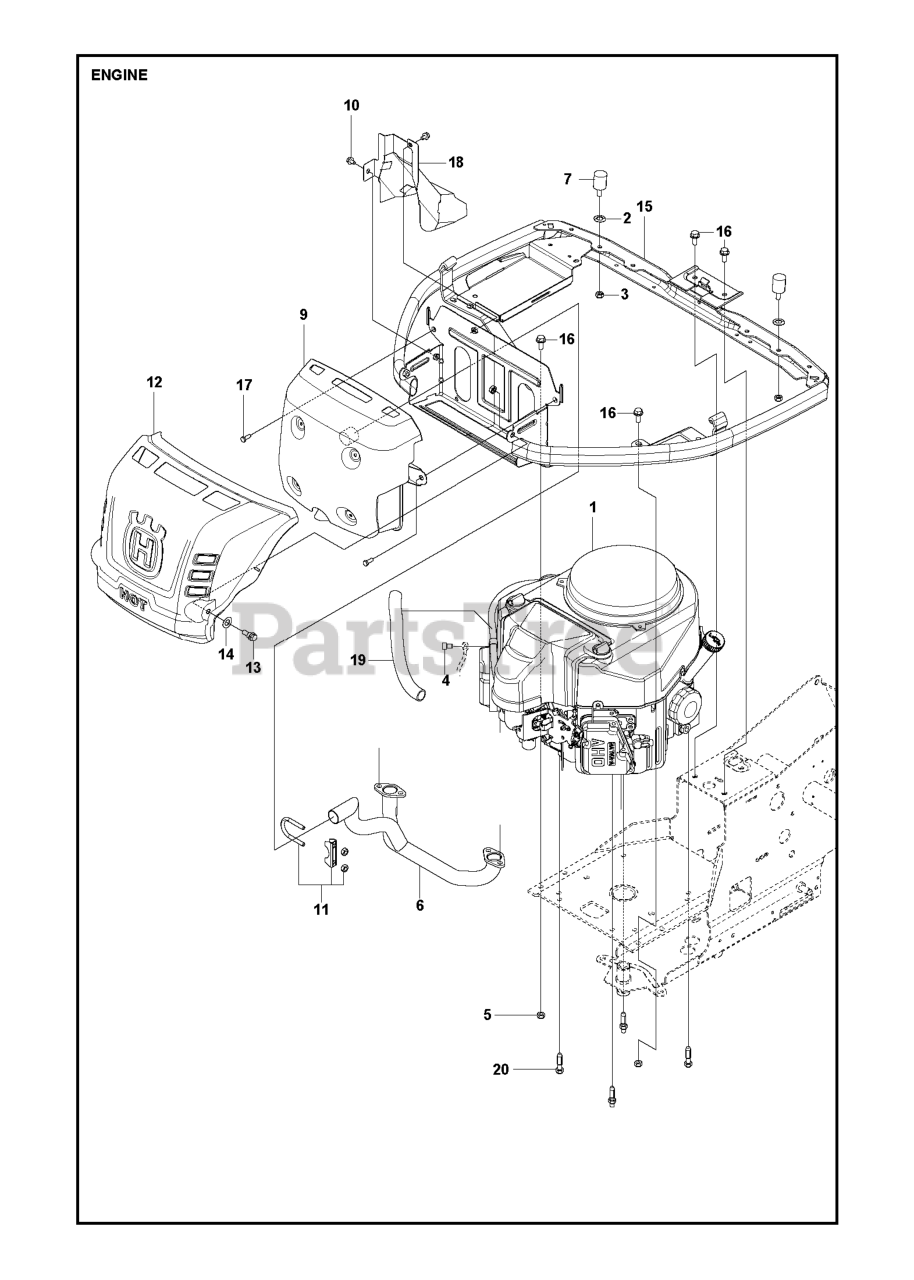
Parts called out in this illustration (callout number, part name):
2	SPRINGWASHER
3	LOCKNUT M8
4	SCREW IHSCM
5	LOCKNUT M8
10	SCREW
10	SCREW EHHFM
11	CLAMP ASSY EXHAUST
12	HEAT SHIELD
14	SPRINGWASHER
17	SCREW EHHFM
20	STUD SCREW
